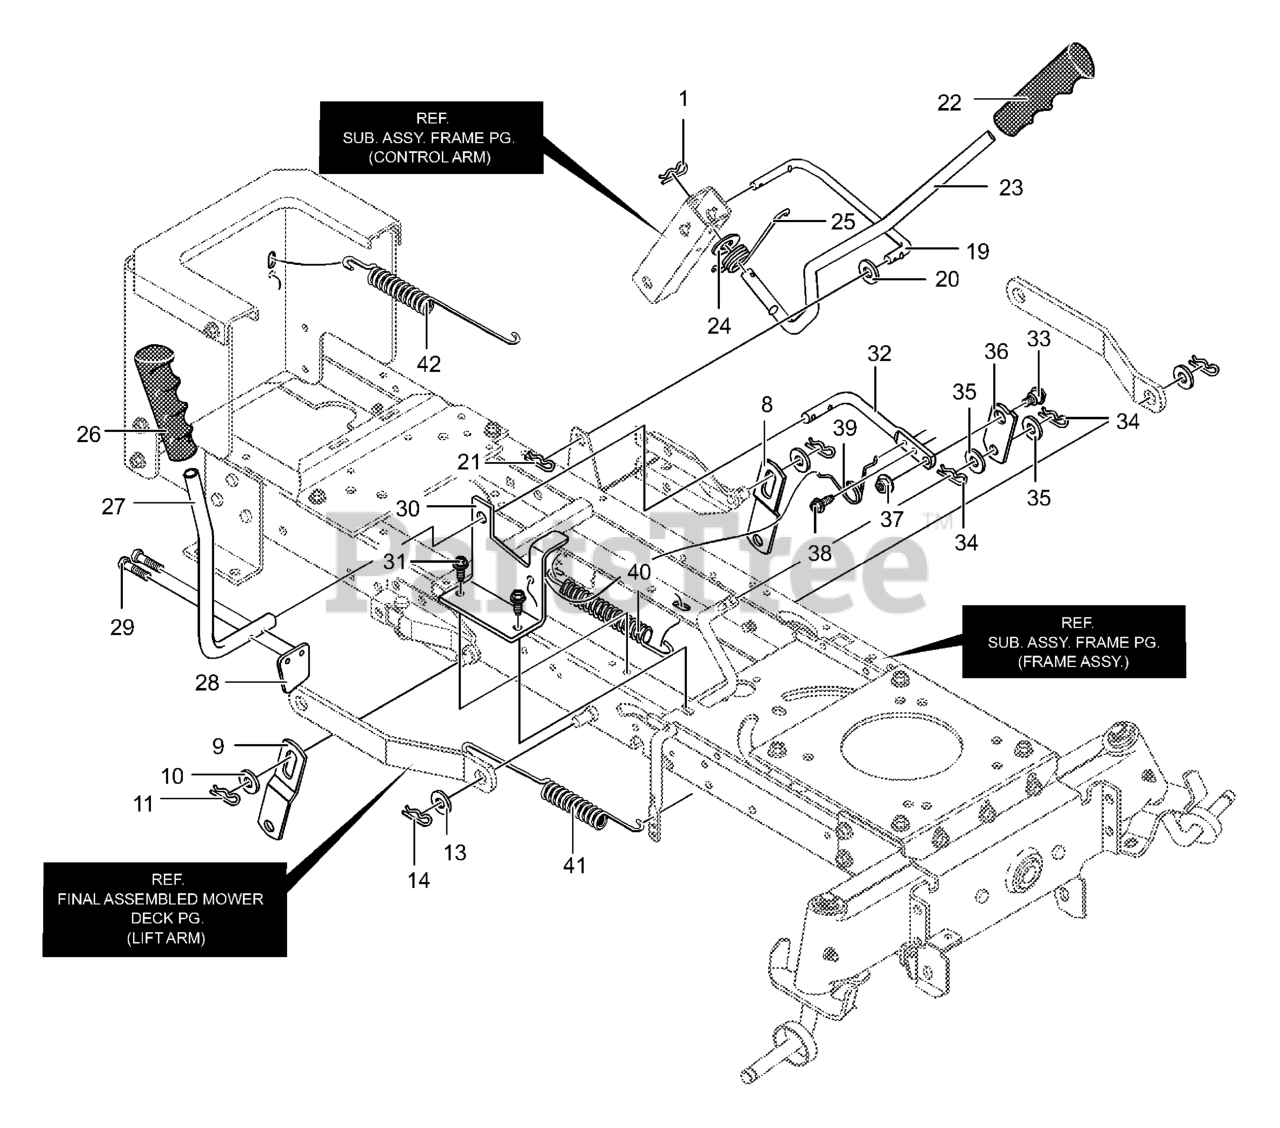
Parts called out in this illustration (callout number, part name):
1	PIN, HAIR
8	LINK, LIFT LH
9	LINK, LIFT RH
10	WASHER, FLAT
11	PIN, HAIR
13	WASHER, FLAT
14	PIN, HAIR
19	LINK LIFT HANDLE
20	WASHER, FLAT
21	PIN, HAIR
22	GRIP, DLX GREY
23	HANDLE, LIFT
24	WASHER, FLAT
25	TORSION SPRING
26	GRIP, PTO DLX GREY
27	PTO HANDLE H26
28	PADDLE, SWITCH
30	BRACKET, PTO
31	SCREW 5/16-18X.50
32	LEVER, PTO
34	PIN, HAIR
35	WASH, FLAT
36	LINK PTO
37	NUT, 3/8-16
38	SCREW 5/16-18X.75
39	TORISON SPRING
40	SPRING, EXTENSION
41	SPRING, EXTENSION
42	SPRING, EXTENSION
